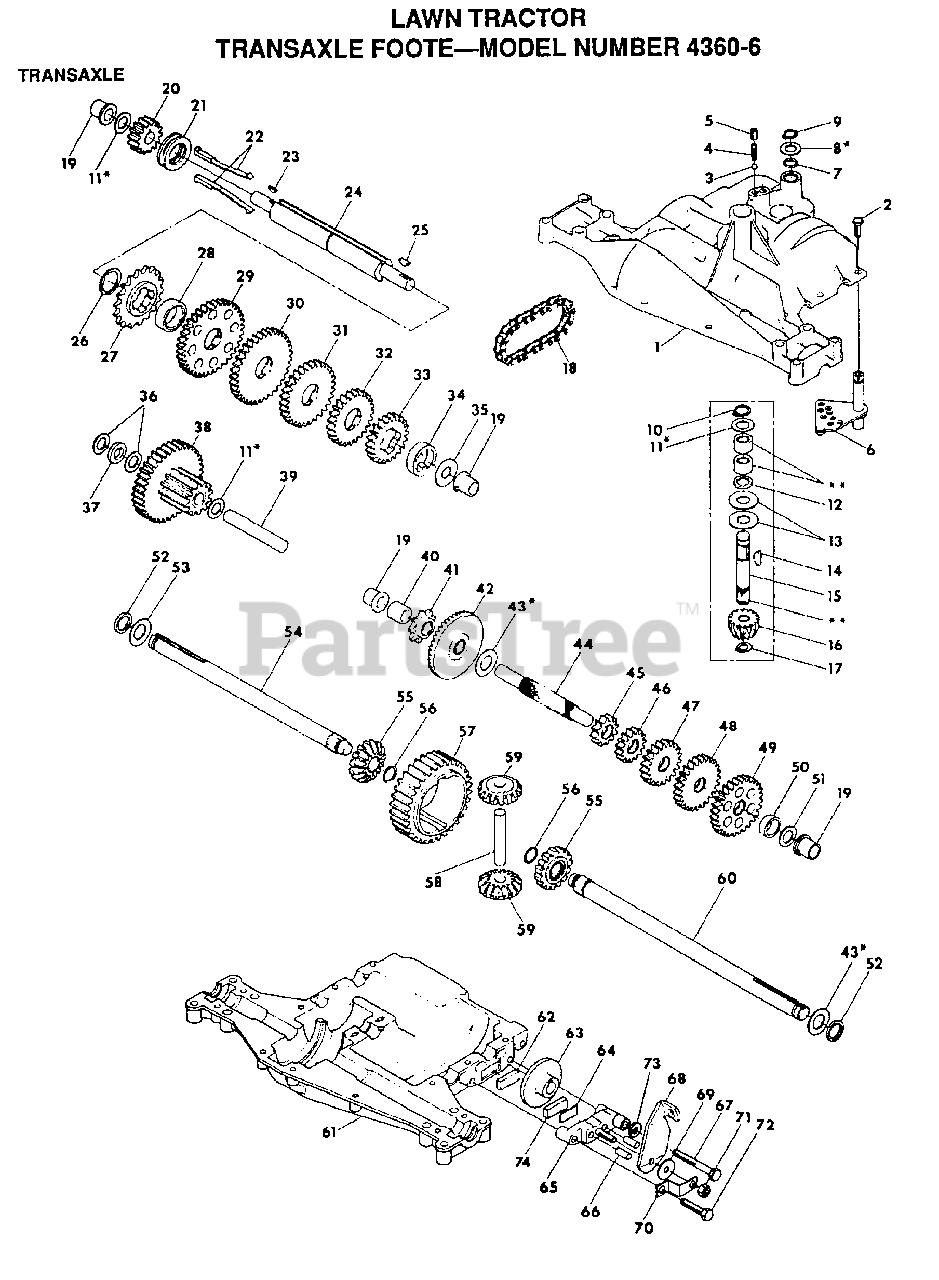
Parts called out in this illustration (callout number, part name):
1	HOUSING UPPER
3	BALL DETENT
4	SPRING, DETENT
5	SCREW, SET
6	ASSY SHIFTER
8	WASHER PLAIN
8A	WASHER PLAIN
8B	WASHER PLAIN
8C	WASHER PLAIN
8D	WASHER PLAIN
8E	WASHER PLAIN
8F	WASHER PLAIN
9	RING RETAINING
10	RING RETAINING
11	WASHER PLAIN
11A	WASHER PLAIN
11B	WASHER, PLAIN .632 X 1.00 X .026
11C	WASHER PLAIN
11D	WASHER PLAIN
11E	WASHER PLAIN
11F	WASHER PLAIN
11G	WASHER PLAIN
11H	WASHER, PLAIN .632 X 1.00 X .060
11I	WASHER PLAIN
13	WASHER, PLAIN .632 X 1.38 X .046
14	KEY WOODRUFF #9
15	ASSY KIT INPUT SHAFT
16	PINION, BEVEL, 14 TEETH
17	RING, RETAINING
18	CHAIN, 24 PITCHES
19	BEARING, FLANGE
20	GEAR SPUR, 14 TEETH
21	COLLAR CLUTCH
22	KEY CLUTCH
23	KEY WOODRUFF #3
24	SHAFT INTERMEDIATE
25	KEY, WOODRUFF, #61
26	RING, RETAINING
27	SPROCKET, 18 TEETH
29	GEAR, SPUR, 37 TEETH
30	GEAR, SPUR, 30 TEETH
31	GEAR, SPUR, 25 TEETH
32	GEAR, SPUR, 22 TEETH
35	WASHER, PLAIN .640 X 1.37 X .061
36	WASHER, PLAIN .632 X 1.00 X .026
37	SPACER .630 X 1.00 X .169
38	ASSY GEAR COMB 12&35 TEETH
39	SHAFT IDLER
40	SPACER .635 X .875 X .755
41	SPROCKET, 9 TEETH
42	GEAR, BEVEL, 42 TEETH
43	WASHER PLAIN
43A	WASHER PLAIN
43B	WASHER PLAIN
43C	WASHER PLAIN
43D	WASHER PLAIN
43E	WASHER PLAIN
43F	WASHER, PLAIN .758 X 1.25 X .031
43G	WASHER PLAIN
43H	WASHER PLAIN
43I	WASHER PLAIN
43J	WASHER PLAIN
43K	WASHER PLAIN
43L	WASHER PLAIN
44	SHAFT, DRIVE
45	GEAR, SPUR, 12 TEETH
46	GEAR, SPUR, 20 TEETH
47	GEAR, SPUR, 25 TEETH
48	GEAR, SPUR, 28 TEETH
49	GEAR, SPUR, 31 TEETH
51	WASHER, PLAIN .632 X 1.00 X .060
53	WASHER PLAIN
54	AXLE LEFT HAND
55	GEAR, MITER, 15 TEETH
56	RING, RETAINING
57	GEAR, SPUR, 32 TEETH
58	SHAFT, CROSS
59	GEAR, MITER, 15 TEETH
60	AXLE, R.H.
61	HOUSING LOWER
62	PUCK, FRICTION
63	DISC, BRAKE
65	JAW, BRAKE
66	PIN, DOWEL
67	SCREW TAPPING
68	LEVER, ACTUATING
69	WASHER, PLAIN .321 X 1.00 X .055
70	BRACKET, ANTI-ROTATION
71	LOCKNUT 5/16-24
72	SCREW TAPPING
73	WASHER PLAIN
74	PUCK, FRICTION
